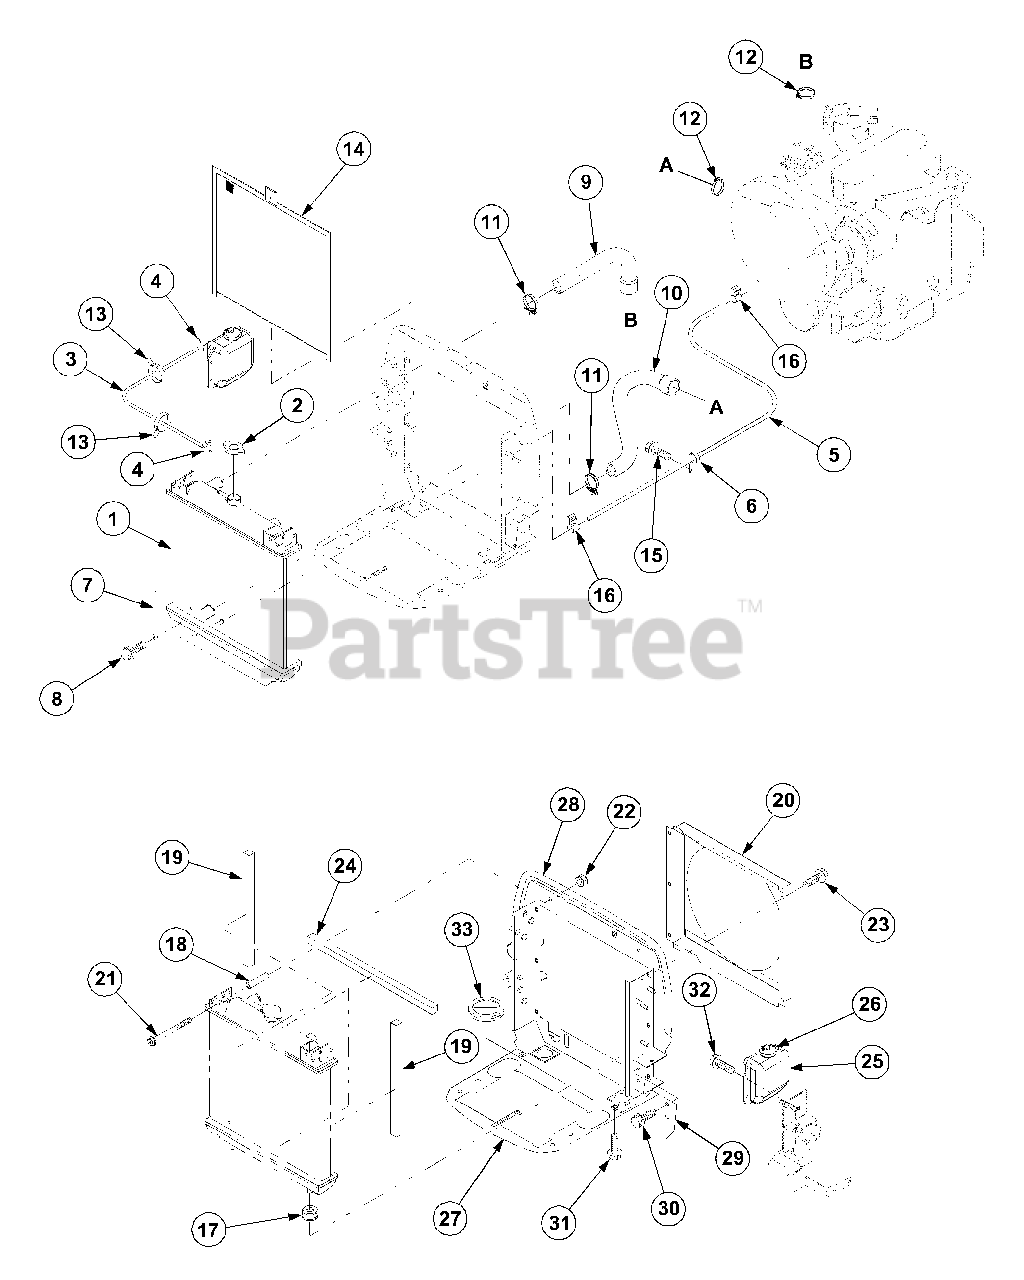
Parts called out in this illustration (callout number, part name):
1	Radiator C Comp
8	Bolt,w/Washer
15	Bolt,w/Washer
23	Bolt,w/Washer
27	Bracket,Radiator
28	Weather Strip
30	Bolt,w/Washer
31	Bolt,w/Washer
32	Bolt,w/Washer
